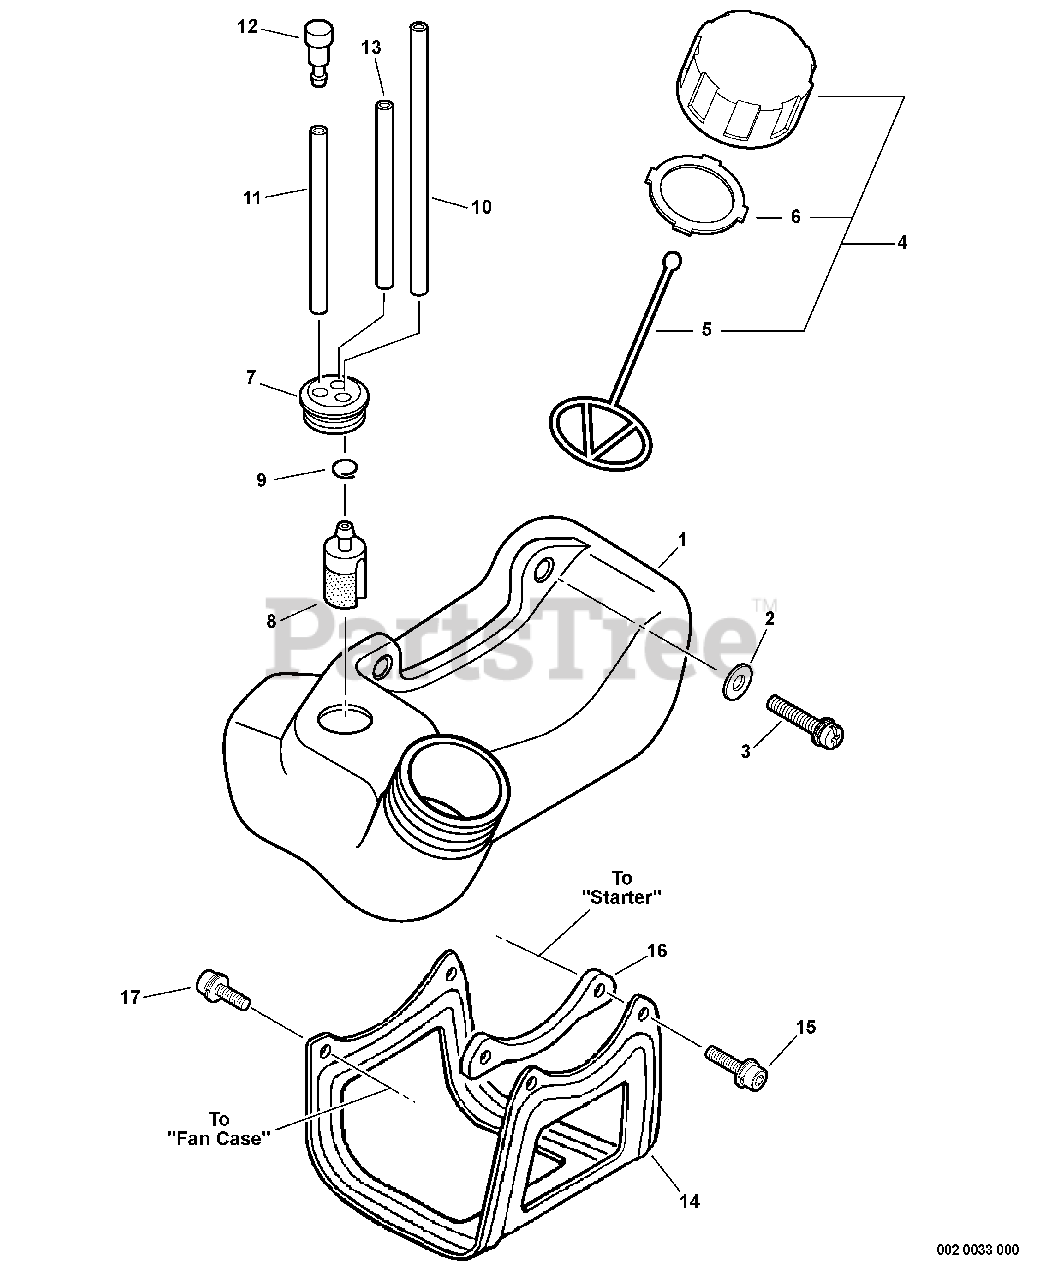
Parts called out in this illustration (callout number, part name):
1	FUEL TANK ASSY
2	WASHER - 5
3	SCREW - 5X20
4	CAP ASSY - ORANGE
5	CONNECTOR, CAP
6	GASKET, CAP
7	GROMMET
8	FILTER, FUEL
9	CLIP - 6
10	PIPE - 3X5X180 -- BLACK
11	PIPE - 3X5X70 -- BLACK
12	VENT, FUEL TANK
13	PIPE - 3X6X80 -- CLEAR
14	GUARD, FUEL TANK
15	SCREW - 4X20
17	SCREW - 4X16
